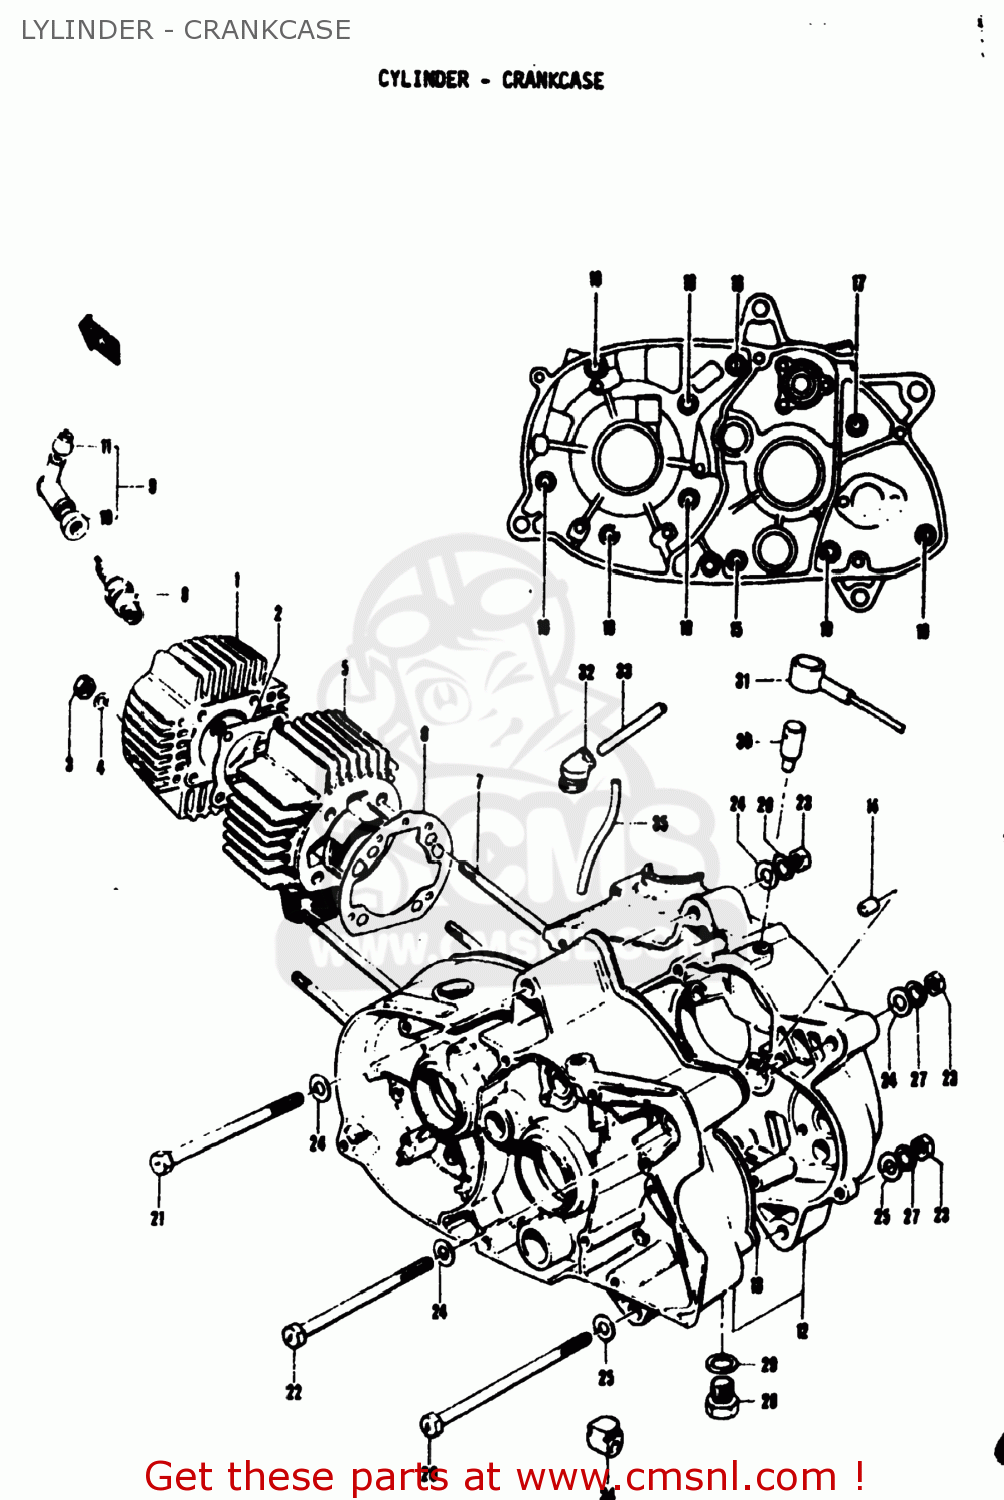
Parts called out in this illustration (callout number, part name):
1	HEAD,CYLINDER
2	GASKET,CYLINDER HEAD (NAS)
3	NUT
4	WASHER
5	CYLINDER
6	GASKET,CYLINDER (MCA)
7	BOLT,STUD
8	SPARK PLUG
9	CAP,SPARK PLUG
10	SEAL,SPARK PLUG
11	SEAL,SPARK PLU
12	CRANKCASE SET
13	GASKET,CRANKCASE (MCA)
14	PIN
15	SCREW
16	SCREW (6X45)
17	SCREW
18	SCREW (6X35)
19	SCREW
20	BOLT 8X110
21	BOLT 8X105
22	BOLT 8X100
23	NUT
24	WASHER
25	WASHER
26	WASHER,LOCK,8.
27	LOCK WASHER
28	PLUG
29	GASKET(14X19.2X2) (NAS)
30	PLUG,TRANSMISSION BREATHER
31	PLUG,BREATHER
32	GROMMET
33	HOSE
34	GROMMET
35	HOSE
